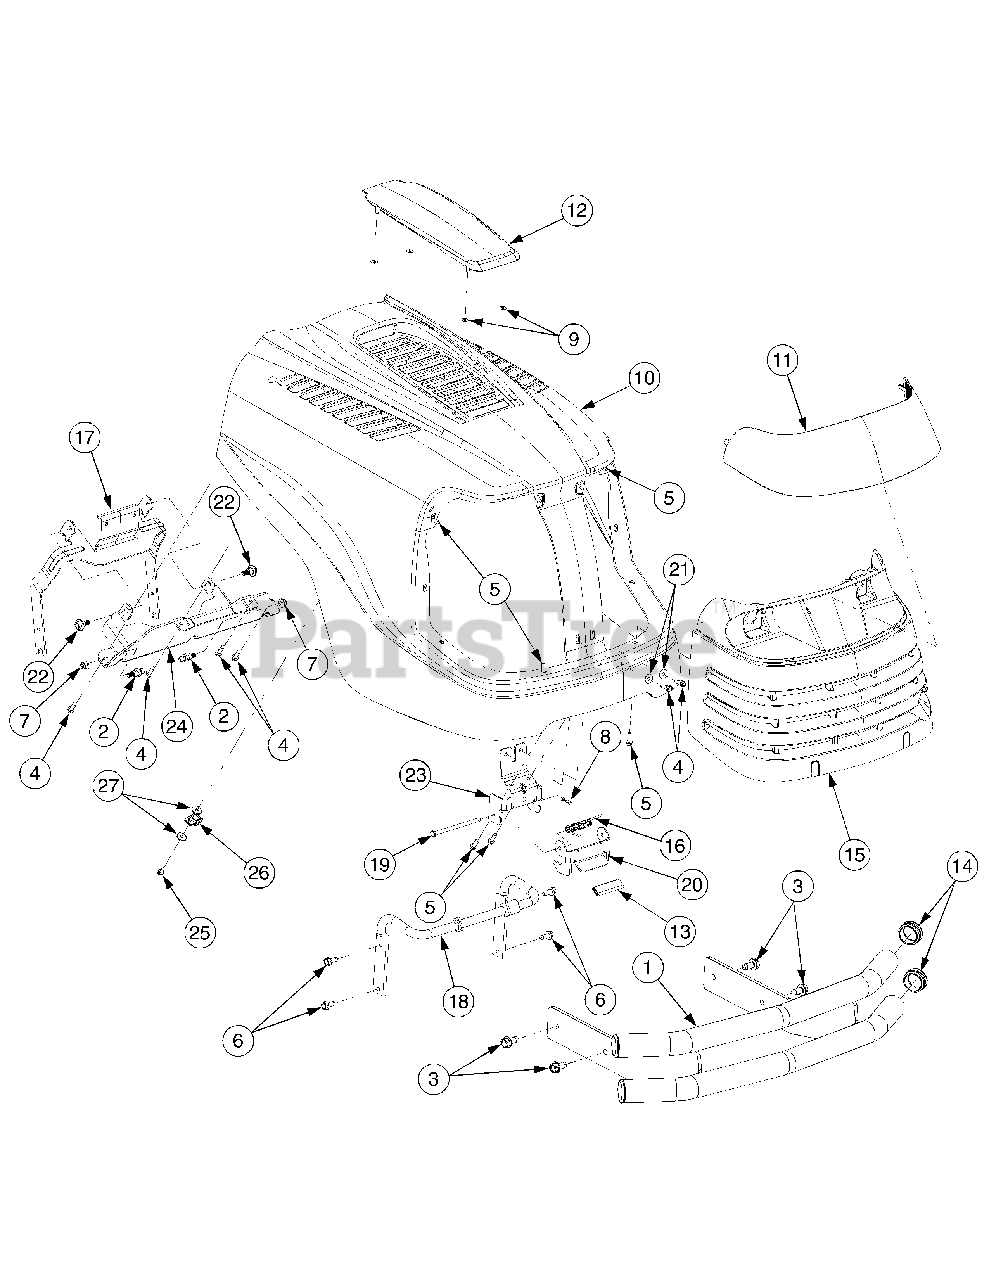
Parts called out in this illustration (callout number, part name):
3	Screw, Hx Washer Hd Tapp 3/8-16 x.750
4	Screw, Hx Washer Hd Tapp 1/4-20 x .750
5	Screw, 1/4-15 x.750
6	Screw, Hx Washer Hd Tapp 5/16- 18 x.750
7	Nut, Flange Lock, 5/16-18 GR5
8	Pin, Cotter,.072 Dia. x 1.13
9	Nut, Push, .25 ID x .50 OD
10	Hood, Service Kit
10	Hood
10	Graphic, Cub Cadet RH
10	Graphic, Cub Cadet LH
10	Graphic, GT2550 LH
10	Graphic, GT2550 RH
11	Lens
12	Cover, Hood
13	Vinyl Strip, 2.5"
14	Cap, Bumper
15	Grill
15	Reflector, Headlight
16	Latch Spring
18	Hood Latch Rod
19	Rod,.250 Dia. x 4.55
20	Latch Pivot Bracket
21	Washer, Flat, .26 x .72 x .06
22	Screw, Shoulder, .43 x .29;TT:5/16-18
23	Latch Plate
25	Screw, Hx Wash, Hd. AB, 10-16 x .5
26	Clamp, 9/16
27	Washer, Flat, .194 x .62 x .063
